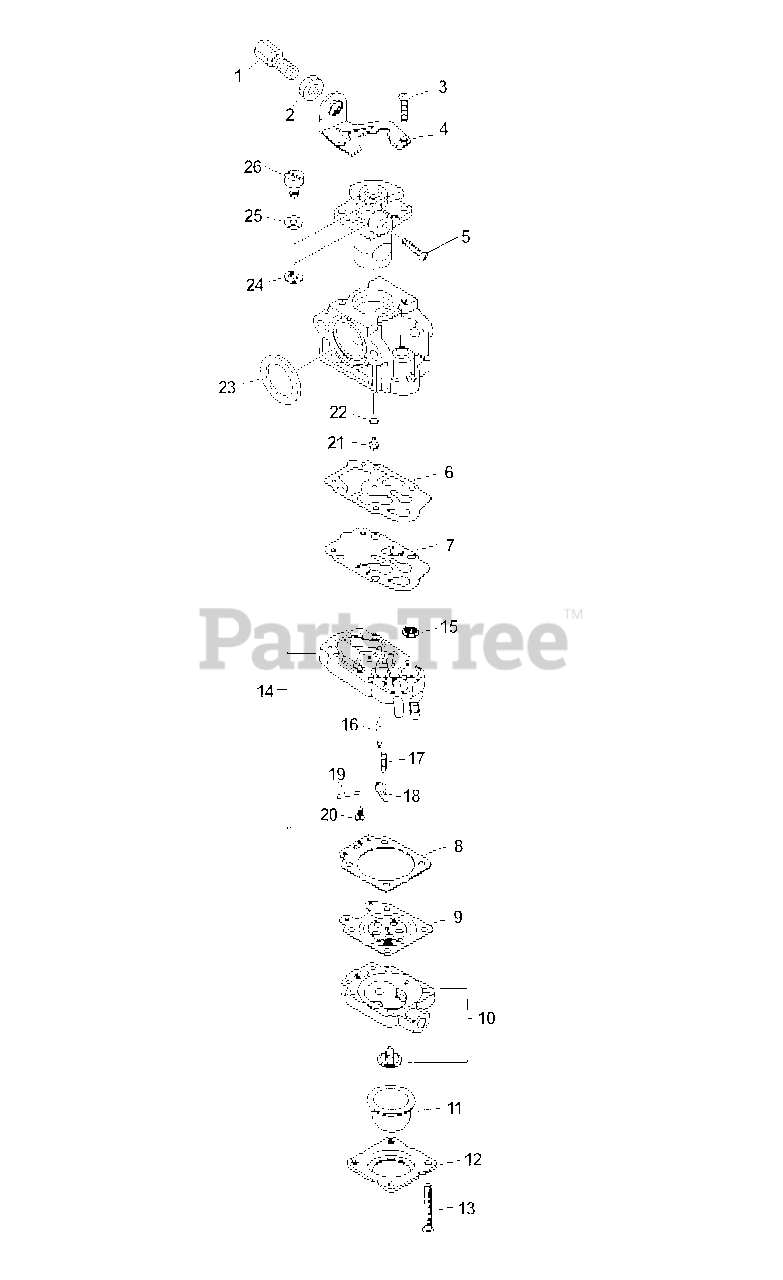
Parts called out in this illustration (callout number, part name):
1	NUT, CABLE ADJUST
4	BRACKET, THROTTLE CABLE
5	SCREW, IDLE ADJUST
6	GASKET, PUMP
7	DIAPHRAGM, PUMP
8	GASKET, METERING
9	DIAPHRAGM, METERING
10	PURGE BASE ASSY
11	BULB, PURGE
12	RETAINER, PURGE BULB
13	SCREW, PUMP COVER
14	BASE, PURGE
15	STRAINER
16	VALVE, INLET NEEDLE
17	SPRING, METERING LEVER
18	LEVER, METERING
19	PIN, METERING LEVER
20	SCREW, METERING LEVER PIN
21	JET, MAIN
23	SEAL
24	RING, RETAINING
